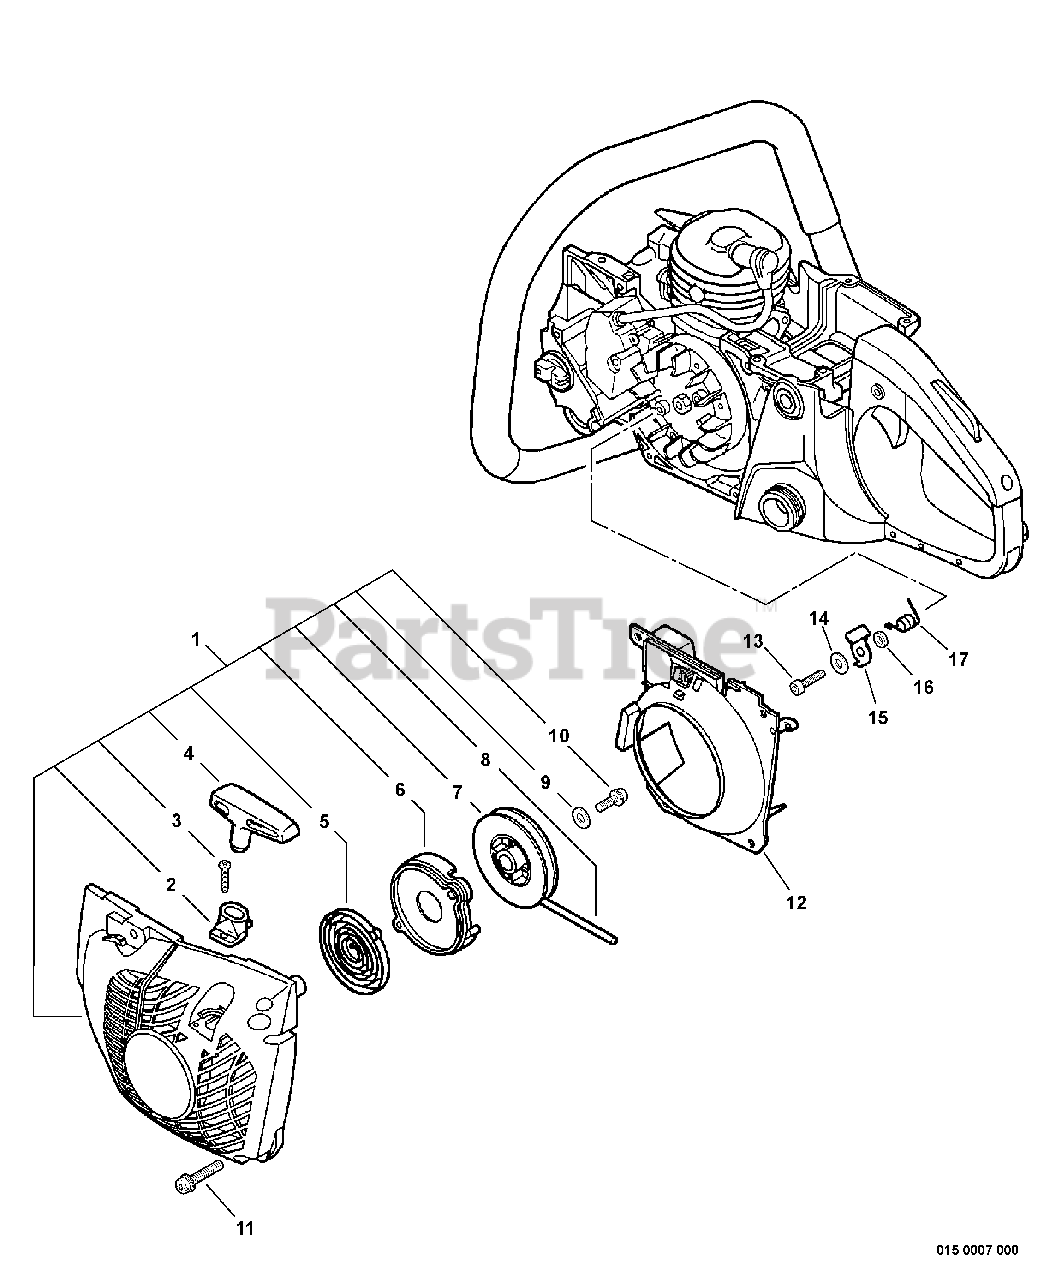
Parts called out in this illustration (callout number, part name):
1	STARTER ASSY, RECOIL
2	GUIDE, ROPE
3	SCREW 3×14
4	GRIP, STARTER
5	SPRING, RECOIL
6	PLATE, STARTER
7	REEL, ROPE
8	ROPE, STARTER
9	WASHER 5.2×16×1.0
10	SCREW 5×12
11	SCREW 5×18
12	COVER, FAN
13	BOLT 5×14
14	WASHER 5.5×12×0.8
15	PAWL, STARTER
16	SPACER 5.2×8×2.1
17	SPRING, TORSION
